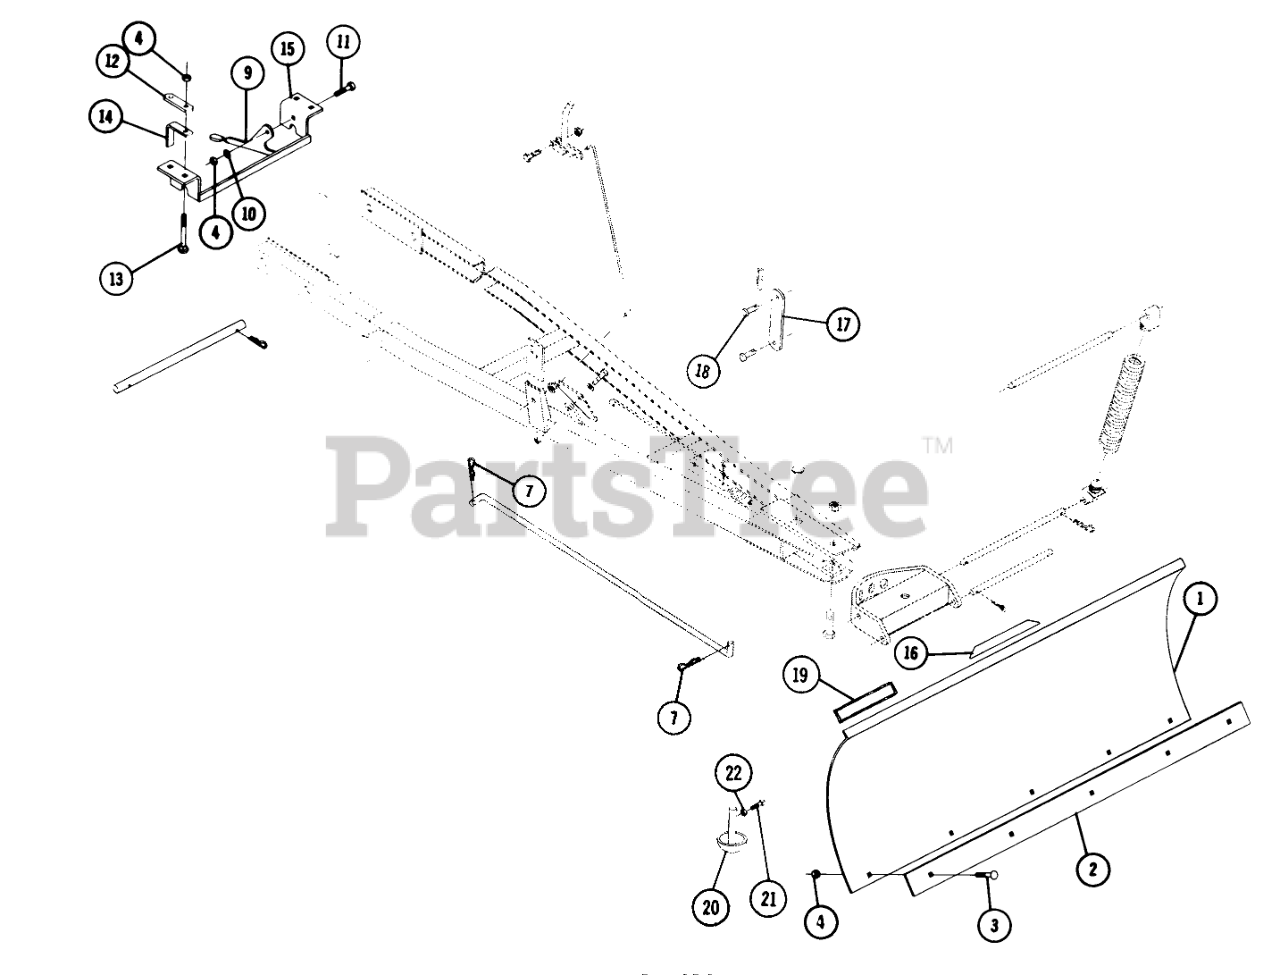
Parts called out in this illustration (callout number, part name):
1	Assy. Blade
2	PLATE-BLADE EDGE
3	Bolt-3/8-16 x 3/4
4	3/8-16 E.S.
6	Hairpin
7	Hairpin
9	Latch Hitch
10	Washer
11	Bolt 3/8-16 x 1
12	Link
13	Bolt-Carr. 3/8-16 x 3 1/2
14	SPACER-BRACKET
15	Hitch Axle Mounting
16	DECAL-WHEEL HORSE
17	Link-Short
19	Decal-Caution
20	Skid
21	Set Screw-3/8-16 x 1
22	3/8-16 Jam Nut
